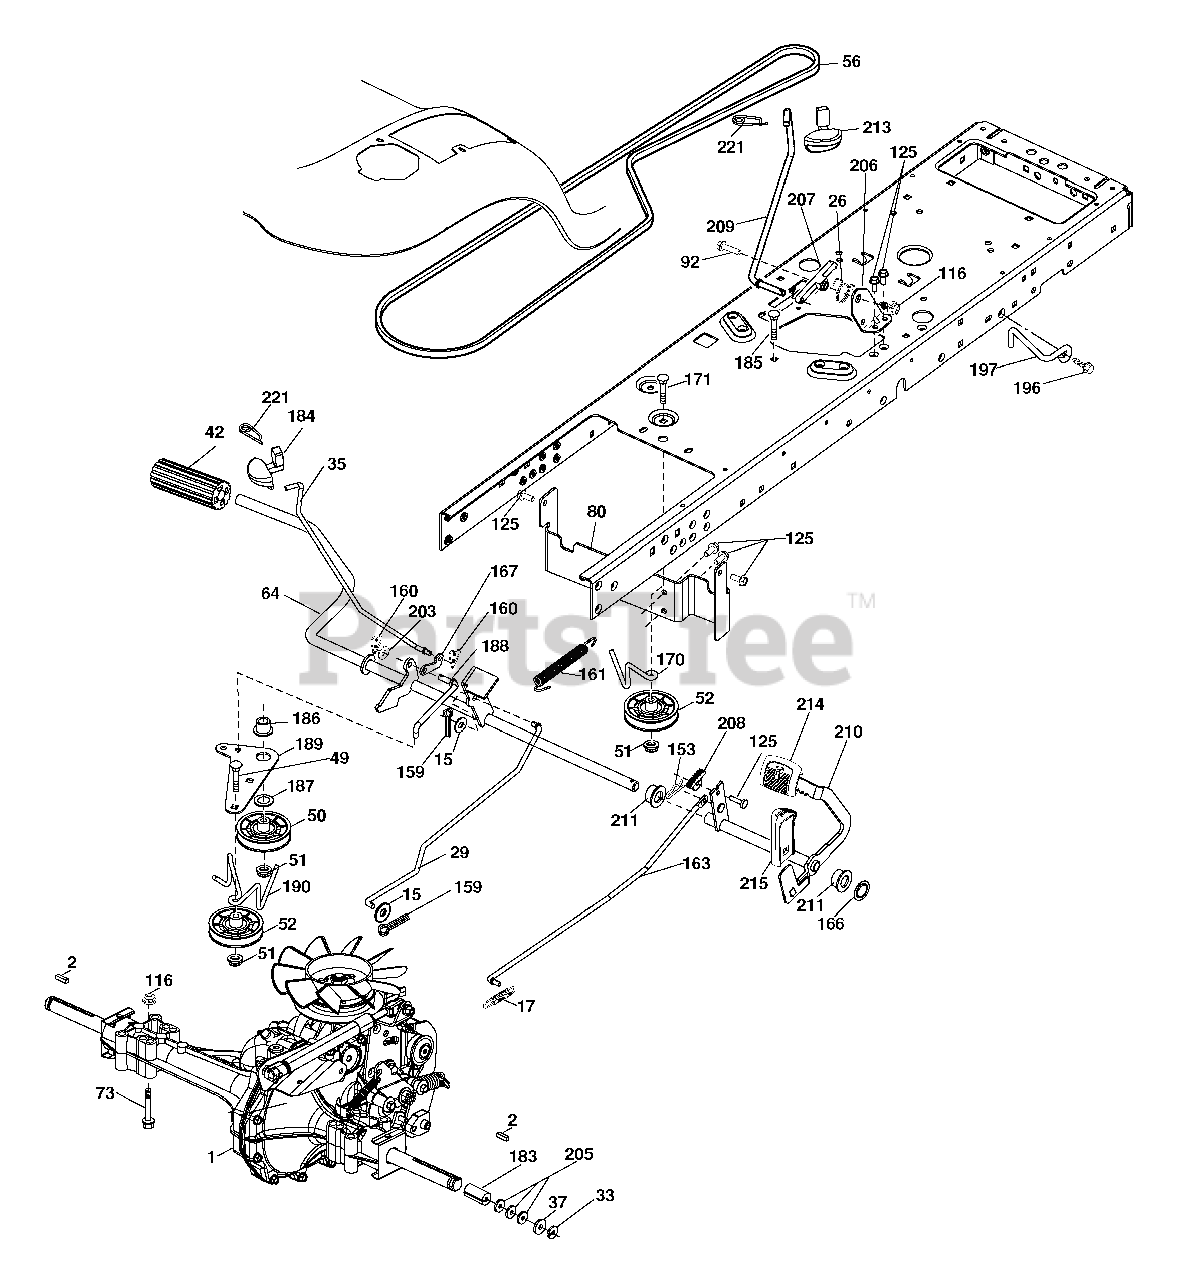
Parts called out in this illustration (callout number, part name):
2	Key
15	Washer 13/32 x 13/16 x 16 Ga.
17	Spring, Brake
29	Rod, Brake
33	Ring E
35	Rod, Brake, Park
37	Washer 25/32 x 1-1/4 x 16 Ga.
42	Cover, Foot Pedal
49	Bolt
50	Pulley Idler Flat
51	Lock Nut 3/8-16
52	Idler V-Groove 910" Offset
56	V-Belt, Drive
64	Shaft Asm. Pedal Brake Control
73	Bolt Hex Flghd 5/16-18 Gr. 5
80	Bracket Strap Torque
92	Bolt Fin Hex 5/16-18 unc x 1.25
116	Nut Lock Hex Flange 5/16-18
125	Screw 5/16-18 x 3/4
153	Retainer Spring
159	Pin Cotter 1/8 x 3/4
160	Retainer Clip
161	Spring, Return, Clutch
163	Rod Pedal Control
166	Nut Push .625
167	Latch Brake Parking
170	Keeper Belt Centerspan
171	Bolt
183	Spacer Axle
184	Handle Parking Brake
185	Bolt
186	Spacer Retainer
187	Washer
188	Link Clutch Ground Drive
189	Bellcrank Ground Drive
190	Keeper Bellcrank Ground Drive
196	Screw 3/8-16 x 1
197	Link Clutch Anti Rotation
203	Washer 11/32 x 11/16 x 16 Ga.
205	Washer 25/32 x 1-5/8 x 16 Ga.
206	Bracket Mount Latch Cruise
207	Latch Control Cruise
208	Gear Sector Control Cruise
209	Rod Control Cruise
210	Rockr Asm. Pdeal Control
211	Bearing Nylon
213	Knob control Cruise
214	Pad Pedal Forward
215	Pad Pedal Reverse
221	Retainer Spring Clip Handle
